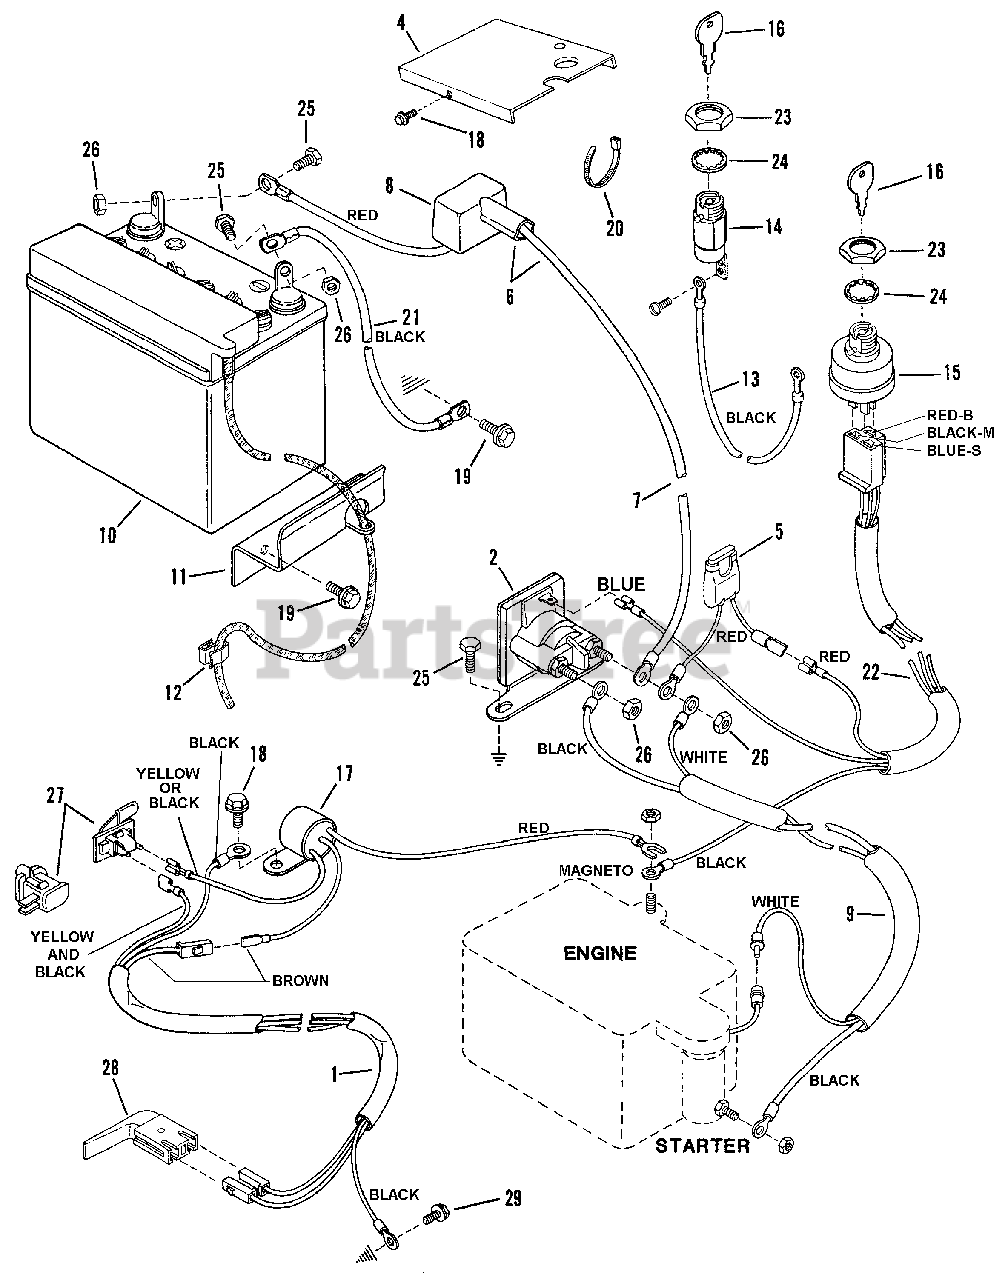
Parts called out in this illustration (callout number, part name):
1	HARNESS, Deck Interlock Wiring
2	SOLENOID
3	HARNESS, Starter Wiring
4	PANEL, Switch
5	HOLDER, Fuse
6	ASSEMBLY, Wire & Cover
7	CABLE, Positive (Red)
8	COVER, Battery Cable
9	HARNESS, Starter Wiring
10	KIT, 12V Dry Charge Battery
11	CLAMP, Battery Retaining
12	CLIP, Battery Hose
13	WIRE, Ground
14	SWITCH, Ignition
15	SWITCH, Ignition
16	KEY, Switch
17	INTERLOCK
18	SCREW, 1/4-20x1/2" Self-Tapping
19	SCREW, 5/16-18x1/2" Self-Tapping
20	CABLE-TIE
21	CABLE, Negative
22	HARNESS, Wiring
23	NUT, 5/8-32 Hex
24	WASHER, 5/8 Internal Tooth Lock
25	SCREW, 1/4-20x5/8" Hex Head Cap
26	NUT, 1/4-20 Hex Lock
27	SWITCH, Shift Interlock
28	SWITCH, Deck Interlock
29	SCREW, #10-24 x 1/2" Hex Washer Self-Tap (Torx)
